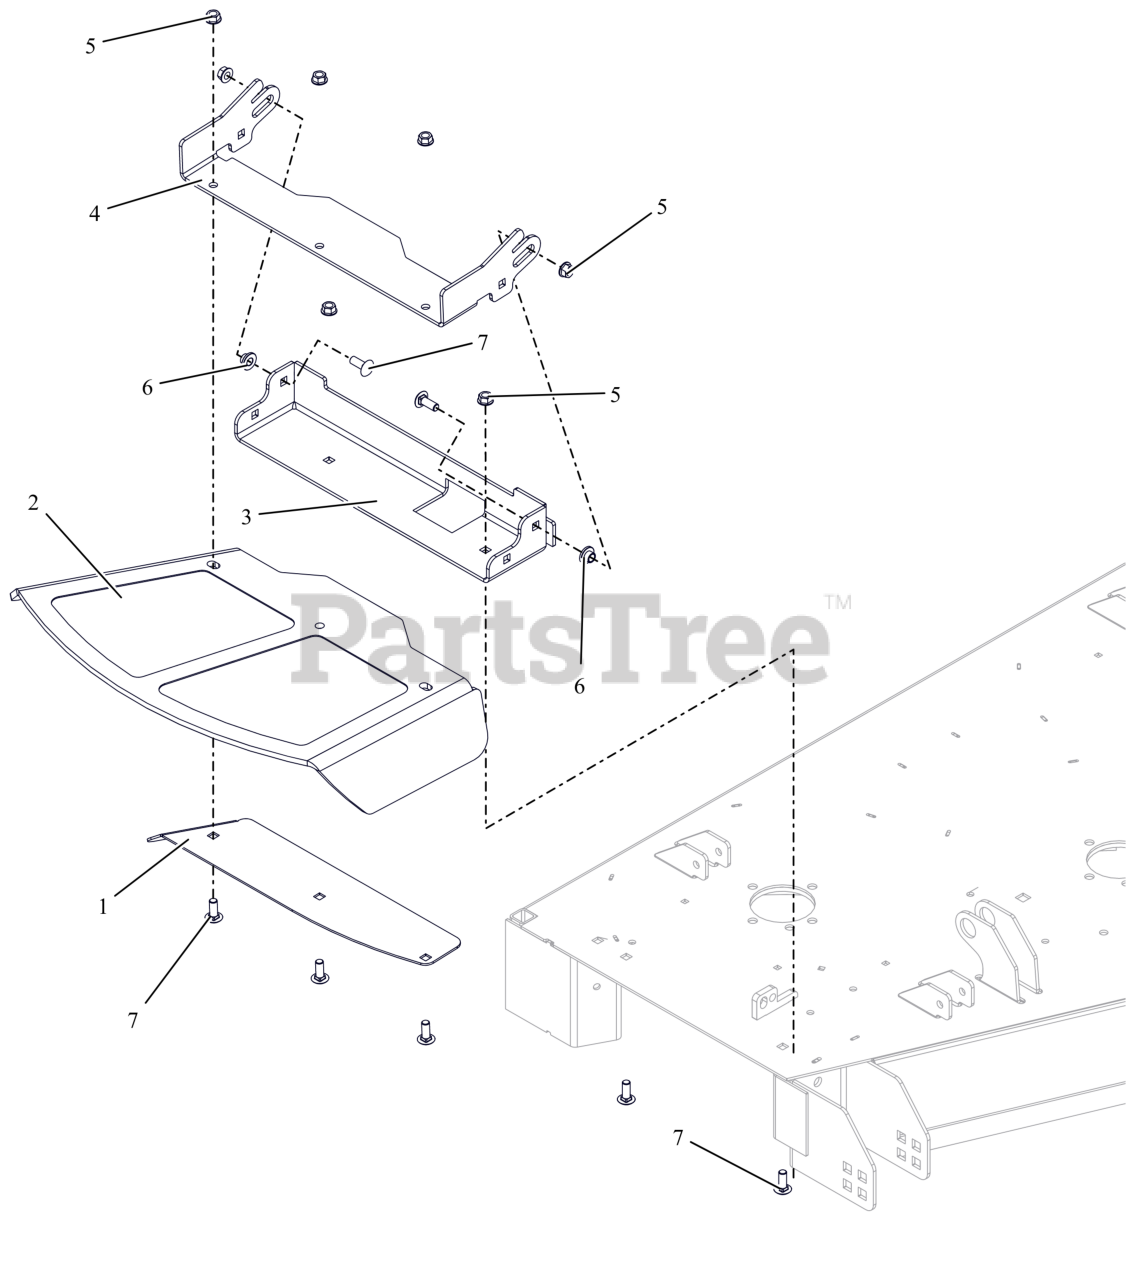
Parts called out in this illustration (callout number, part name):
1	DISCHARGE CHUTE CLMP PLT-RED
2	CHUTE, FORMED RUBBER DISCHARGE
3	BASE, DISCH CHUTE MTG W/SAFETY
4	BRKT- CHUTE MTG
5	NUT-LK-CTR-FLG .375-16 GF ZCC
6	BSHG-FLG .385X.500X.875X.406
7	BLT,RHSSN .38-16X1.00 G5 ZCC
